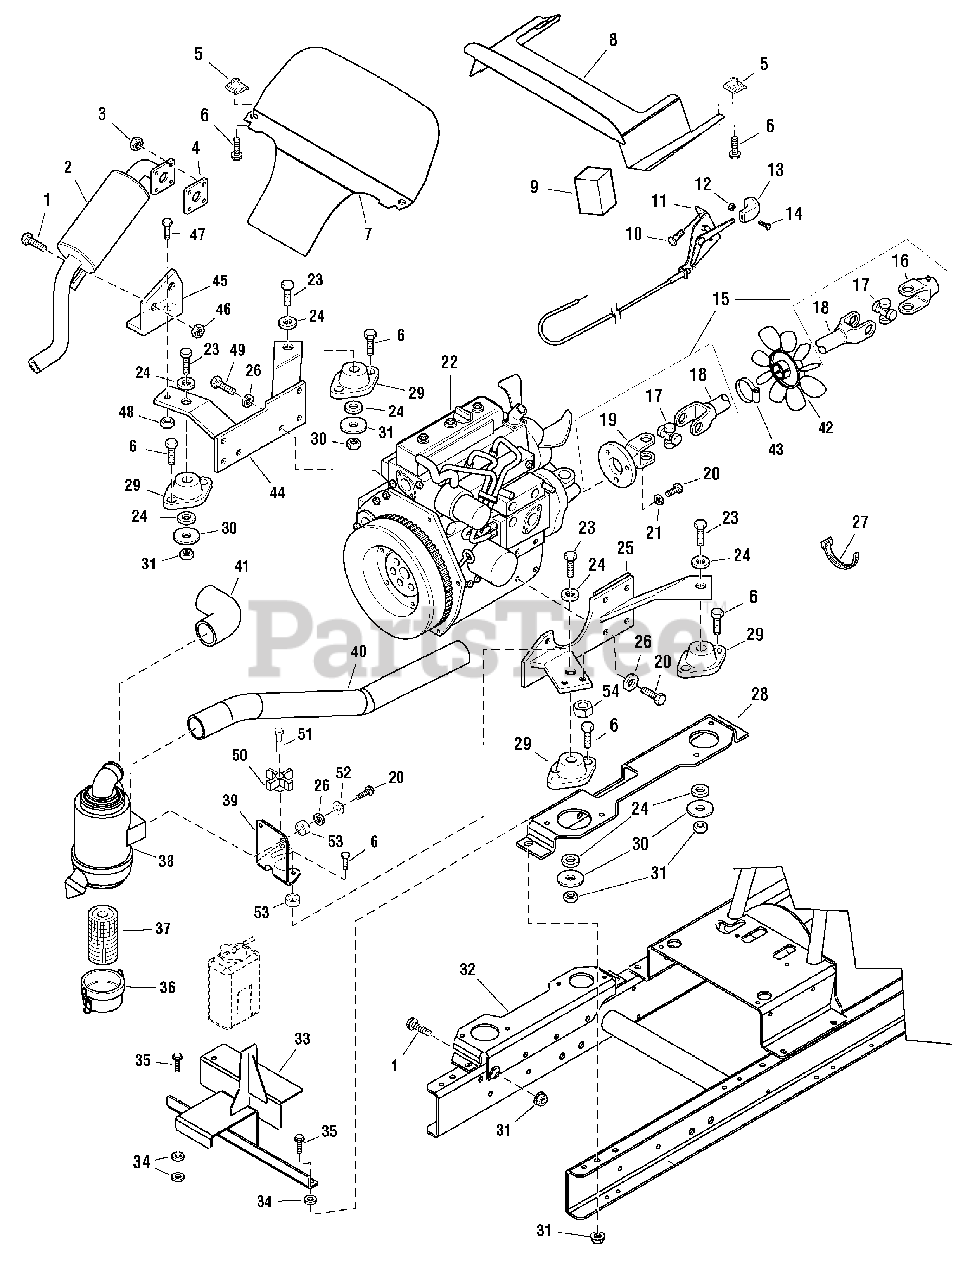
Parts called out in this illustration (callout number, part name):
1	SCREW, Hex Whiz Lock Flange, 3/8-16 x 1
2	MUFFLER
3	* NUT
4	* BRACKET
5	NUT, Speed, 1/4-20, U Type
6	SCREW, Hex, Washer, Head, Taptite, 5/16-18 x 3/4
7	SHIELD, Hood 18GA
8	BAFFLE, Hood 18GA
9	SEAL, Foam 1-1/2 x 1-1/2, 2.8LG
10	SCREW, Hex, Washer Head, Taptite, 12-24 x 5/8
11	CONTROL, Throttle
12	NUT, Hex Lock, 10-24
13	KNOB, Slot
14	SCREW, Phillips, Pan Head, #10-24 x 1
15	SHAFT ASSEMBLY, Drive
16	YOKE, Drive Shaft
17	CROSS & BEARING KIT, Includes Grease Fitting
18	YOKE & TUBE ASSEMBLY
19	YOKE & FLANGE, Drive Shaft
20	CAPSCREW, Hex Head,
21	LOCKWASHER, Spring, 5/16
22	* ENGINE, 26.5HP Briggs & Stratton Diesel
23	CAPSCREW, Hex Head, 3/8-16 x 2-1/2, G5
24	WASHER, 3/8
25	MOUNT ASSEMBLY, Engine, L.H.
26	LOCKWASHER, Spring, 5/16
27	TIE, Self Locking, 7.31LG
28	MOUNT, Engine, L.H.
29	MOUNT, Engine, Rear
30	WASHER, 1/2
31	NUT, Hex, KEPS, Conical Washer, 3/8-16
32	MOUNT, Engine, R.H.
33	HOLD DOWN ASSEMBLY, Battery
34	WASHER, 3/8
35	SCREW, Hex, Whiz Lock, Flange, 3/8-16 x 1-1/4
36	COVER ASSEMBLY, Air Cleaner
37	FILTER, Air Cleaner
38	AIR CLEANER ASSEMBLY
39	BRACKET, Air Cleaner
40	HOSE, Air Inlet, 28LG
41	HOSE, Inlet
43	CLAMP, Hose, Worm
44	MOUNT ASSEMBLY, Engine R.H.
45	BRACKET, Muffler
46	NUT, Hex, Flange, 3/8-16, ESNA
47	SCREW, Hex, Whiz Lock, Flange 5/16-18 x 1-1/4
48	NUT, Hex, Flange, 5-16-18, ESNA
49	SCREW, M8 - 1.25 x 20mm, Hex Head
51	CAPSCREW, Hex Head 5/16-18 x 1-1/2
52	WASHER, 5/16
54	NUT, Hex, 5/16-18
